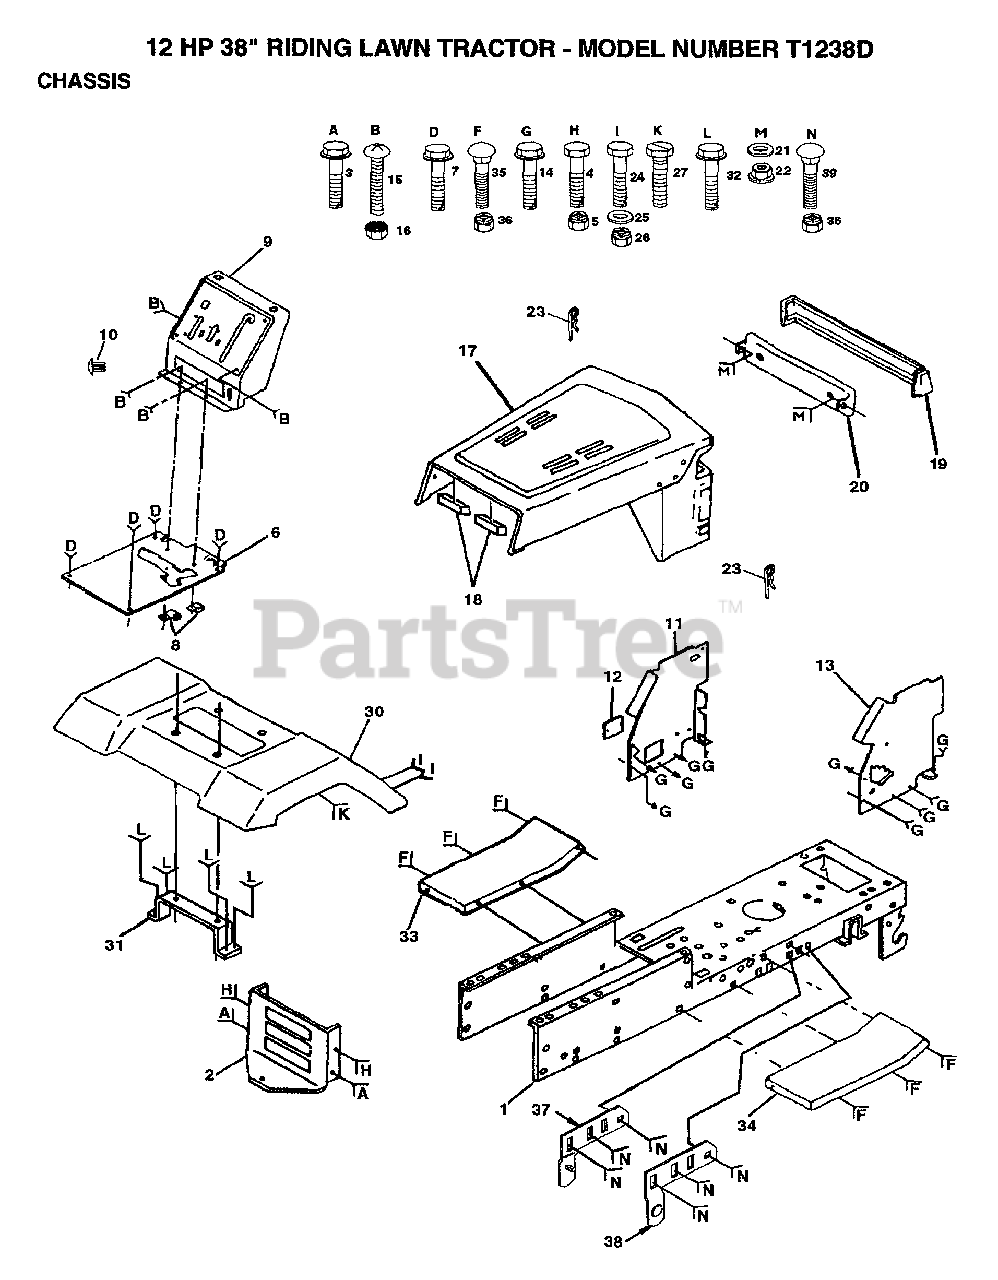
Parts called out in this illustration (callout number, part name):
2	DRAWBAR LT/YT
3	SCREW
5	NUT
7	SCREW LT
8	CLIP T
10	PLUG BUTTON T
11	PANEL DASH LH
12	COVER ACCESS
14	SCREW LT
15	SCREW
17	HOOD/GRILL ASM
21	WASHER PM
22	PAL NUT LT
23	SPRING.RETAINER
25	WASHER
27	SCREW LT
32	SCREW
33	FOOTREST LH
34	FOOTREST
35	BOLT
37	BRKT ASM PIVOT LH
38	BRKT ASM PIVOT RH
39	BOLT
